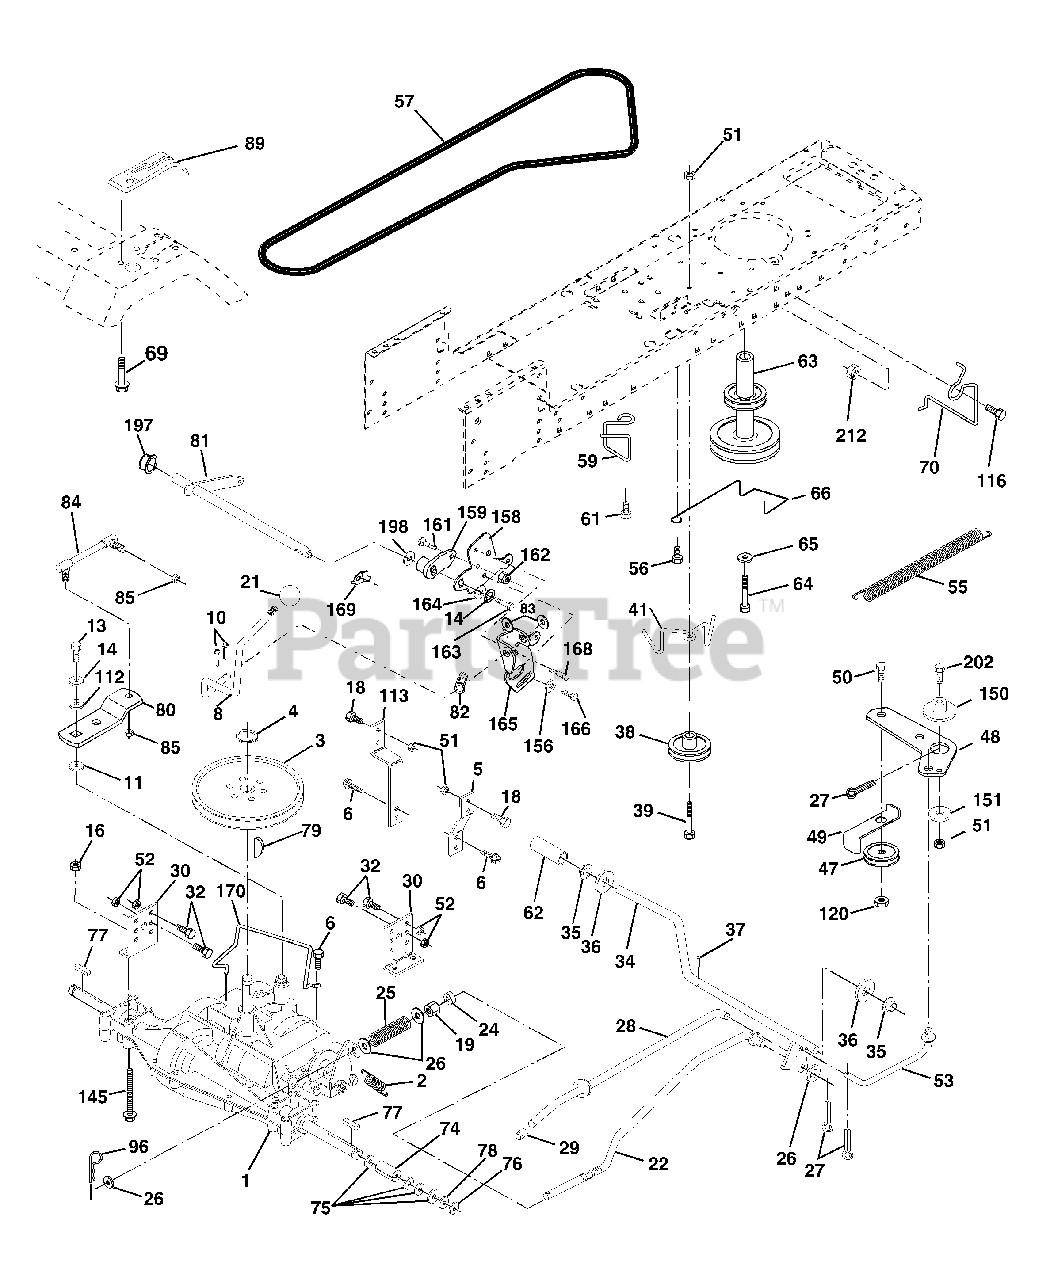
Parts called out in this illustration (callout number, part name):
2	Spring Return Brake T/a Zinc
3	Pulley Transaxle 18" tires
4	Ring Retainer # 5100-62
5	Strap Torque 30 Degrees
6	Screw 5/16-18 X 3/4
8	Rod Shift Fender Adjust Lt
10	Pin Cotter 1/8 X 1 Cad
11	Washer Plate Shf 388 Sq Hole
13	Bolt 1/4-28 Unf Gr 8 W/Patch
14	Washer Lock Hvy Helical
16	Nut Lock Hex w/ins 5/16-18
18	Bolt, Fin Hex 3/8-16 UNC x 1 Gr. 5
19	Nut Lock 3/8-16 Unc
21	Knob
22	Rod Brake Blk Zinc 26 840
24	Nut Hex Jam 3/8-16 Unc
25	Spring Rod Brake 2 00 Zinc
26	Washer 13/32 X 13/16 X 16 Ga
27	Pin Cotter 1/8 X 3/4 Cad
28	Rod Brake Parking LT/YT
29	Cap Brake Parking
30	Bracket Mtg Transaxle
32	Bolt Hex Hd 5/16-18unc X 3/4
34	Shaft Asm Pedal Foot
35	Bearing Nylon Blk 629 Id
36	Washer 21/32 X 1 X 16 Ga
37	Pin Roll 3/16 X 1"
38	Pulley Composite Flat
39	Bolt Fin Hex 3/8-16 unc X 3
41	Keeper Belt Flat Idler
47	Pulley Idler V Groove Plastic
48	Bellcrank Asm
49	Retainer Belt Style Spring
50	Bolt Hex Hd 3/8-16unc X 1-1/2
51	Nut Crownlock 3/8-16 Unc
52	Nut Crownlock 5/16-18 Unc
53	Link Clutch
55	Spring Return Clutch 6 75
56	Screw 3/8-16 x 1-1/4
57	V-Belt Ground Drive 95 25
59	Keeper Belt Span Ctr
61	Screw 3/8-16 x .875
62	Cover Pedal Blk Round
63	Engine Pulley
64	Bolt Hex
65	Washer Lock Hvy Hlcl Spr 7/16
66	Keeper Belt Engine Foolproof
69	Screw Hex wsh Hi Lo 1/4 x 1/2 unc
70	Guide Belt Mower Drive RH
74	Spacer Axle
75	Washer 25/32 X 1 1/4 X 16 Ga
76	E-ring #5133-75
77	Key Square 2 0 X 1845/ 1865
78	Washer 25/32 X 1-5/8 X 16 Ga
79	Key Woodruff #9 3/16 x 3/4
80	Arm Shift
81	Shaft Asm Cross Tapered PMST/20
82	Spring Torsion T/a
83	Washer 17/32 X 3/4 X 16 Ga
84	Link Transaxle PMST/20" Zinc
85	Nut Lock Center 1/4 - 28 FNTHD
89	Console Shift STLT
96	Retainer Spring 1"
112	Washer 9/32 x 3/4 x 10 Ga.
113	Strap Torque LT
116	Bolt Rdhd Sq Neck 3/8-16 x 1
120	Nut Lock Flg. 3/8-16 Unc
145	Bolt Hex FLGHD 5/16-18 Gr. 5
150	Spacer Retainer
151	Washer 13/32 x 2 x 10
156	Washer Srrted 5/16ID x 1.125
158	Bracket Shift Mount
159	Hub Tapered Flange Shift Lt
161	Bolt Rdhd Sqnk 1/4-20 x 3/4 Gr
162	Nut Crownlock 1/4-20 Unc
163	Bolt Hex Fin 1/4-20 Unc x 1 Gr 5
164	Washer 5/8 x .281 x 10 Ga
165	Bracket Pivot Lever
166	Screw 5/16-18 x 5/8
168	Bolt Shoulder 5/16-18 x .561
169	Plate Fastening
170	Keeper Belt Transaxle Gear
197	Nyliner Snap-In
198	Washer Nyliner
202	Bolt Carr Sh 3/8-16 x 1-1/2 Gr. 5
212	Nut Hexflange Lock
